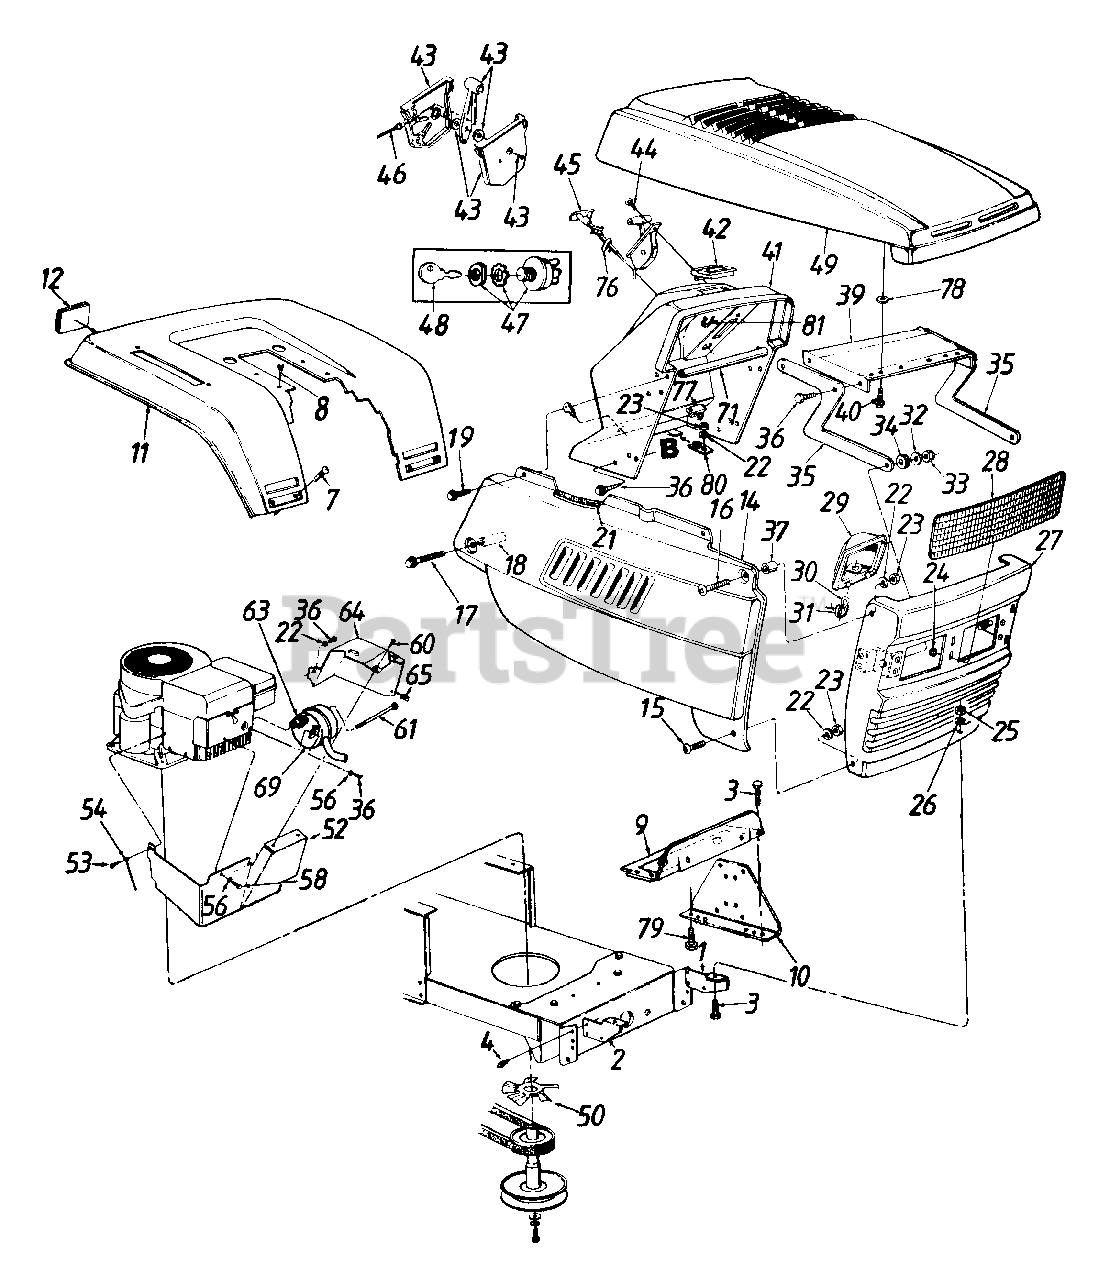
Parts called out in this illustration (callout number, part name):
1	Grille Mtg. Brkt.- L.H.
4	Hex Wash. Hd. Tap Scr. 5/16-18 x .5" Lg.
7	Carriage Bolt 1/4-20 x .5" Lg.
8	Hex Wash. Hd. Tap Scr. 5/16 x .75" Lg.
16	Truss Mach. Scr. 1/4-20 x 1.0" Lg.
17	Hex Wash. TT-Tap Scr. 1/4-20 x 1.75" Lg.
18	Spacer .26" I.D. x 1.32"
19	Hex Rolling Tap Scr. 1/4-20 x .75" Lg.
21	Trim Strip - 12" Lg.
22	L-Wash. 1/4" I.D.
23	Hex Nut 1/4-20 Thd.
24	Speed Nut 5/16" Thd.
25	Hex Nut 5/16-18 Thd.
26	Fl-Wash..344" I.D. x 1" O.D.
29	Headlamp Housing
30	Headlamp
31	Twist Lock Lamp Socket
32	Bell-Wash. .345" I.D. x .88"
33	Hex L-Nut 5/16-18 Thd.
34	Rubber Washer
35	Hood Hinge
36	Hex Wash. Hd. B-Tap Scr. 1/4-20 x .5" Lg.
37	Spacer.262" I.D. x.31"
41	Dash
42	Ammeter
43	Throttle Control Box Ass'y.
44	Mach. Scr. #10 x .44" Lg.
45	Choke Control 23" Lg.
46	Throttle Control Wire 18.5" Lg.
47	Ignition Switch
48	Ignition Key
52	Muffler Heat Shield - Front
53	Truss Mach. Scr. 5/16-18 x .75" Lg.
54	Ground Wire
56	Spr. Wash. 1/4" I.D.
58	Hex Bolt 1/4-20 x 3/8" Lg."
60	Hex B-Tap Scr. #10 x .38" Lg.
61	Shoulder Bolt
63	Exhaust Gaskets
64	Muffler Heat Shield - L.H.
65	Speed Nut #10-24 Thd.
69	Muffler
71	Grille Support Tube
76	Choke Retainer
77	Light Switch
78	Fl-Wash. .406" I.D. x .812" O.D.
79	Hex Bolt 1/4-20 x .62" Lg.
80	Dash Fastening Tab
81	Cable Tie
